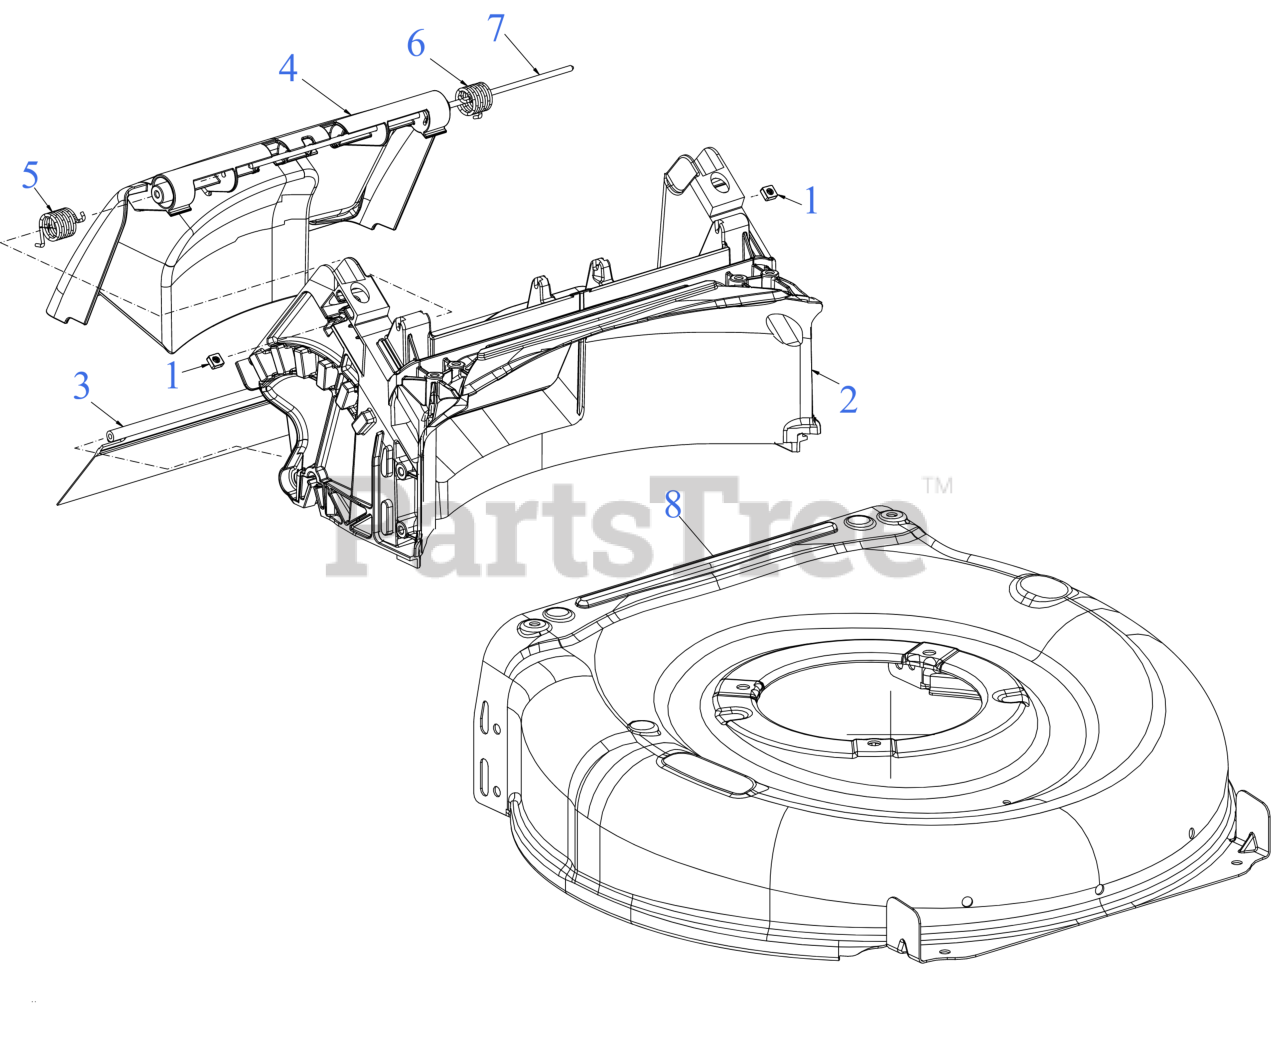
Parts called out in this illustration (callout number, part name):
1	SQUARE NUT 1/4-20
2	REAR DOOR & BAFFLE ASSEMBLY
3	TRAILSHIELD
4	REAR DOOR & BAFFLE ASSEMBLY
5	TORSION SPRING (RH)
6	TORSION SPRING (LH)
7	REAR DOOR PIVOT ROD
